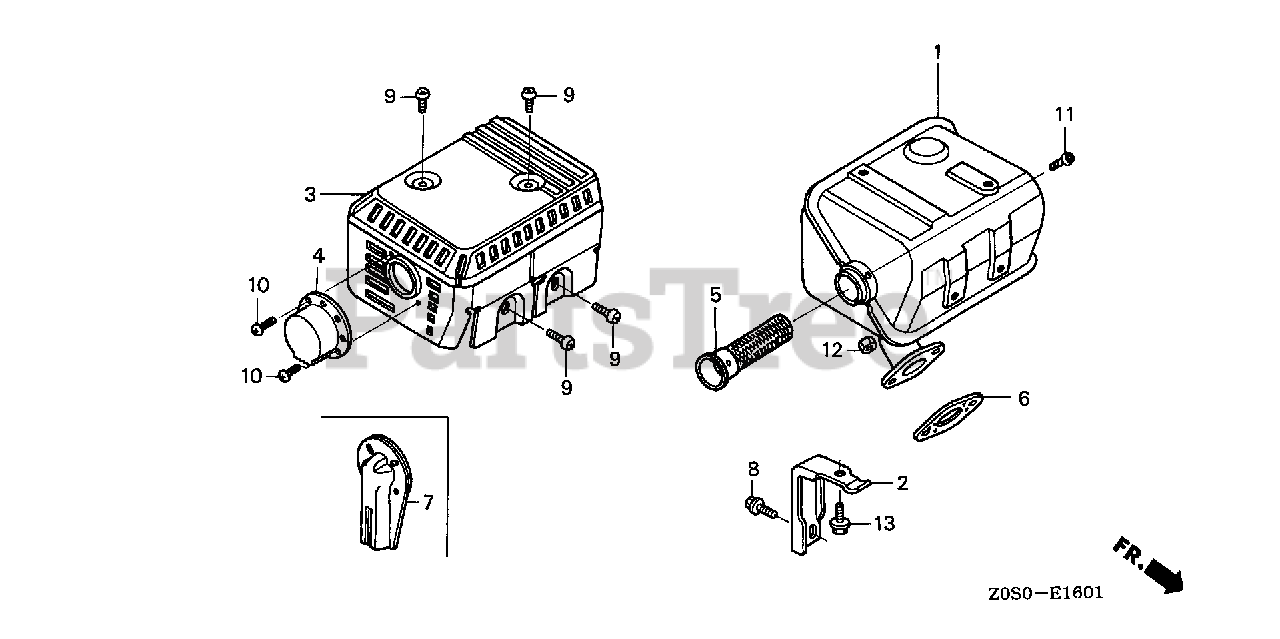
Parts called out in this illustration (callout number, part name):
1	MUFFLER (SILENT)
1	MUFFLER (ARRESTER)
2	STAY, MUFFLER
3	PROTECTOR, MUFFLER (SILENT)
4	CAP, MUFFLER
5	ARRESTER, SPARK
5	ARRESTER, SPARK (SILENT)
6	GASKET, MUFFLER
7	DEFLECTOR, MUFFLER
8	BOLT, FLANGE (6X13) (CT200)
9	SCREW, TAPPING (5X8)
10	SCREW, TAPPING (4X6)
11	SCREW, TAPPING (4X6)
12	NUT, HEX. (8MM)
13	BOLT, FLANGE (6X12)
